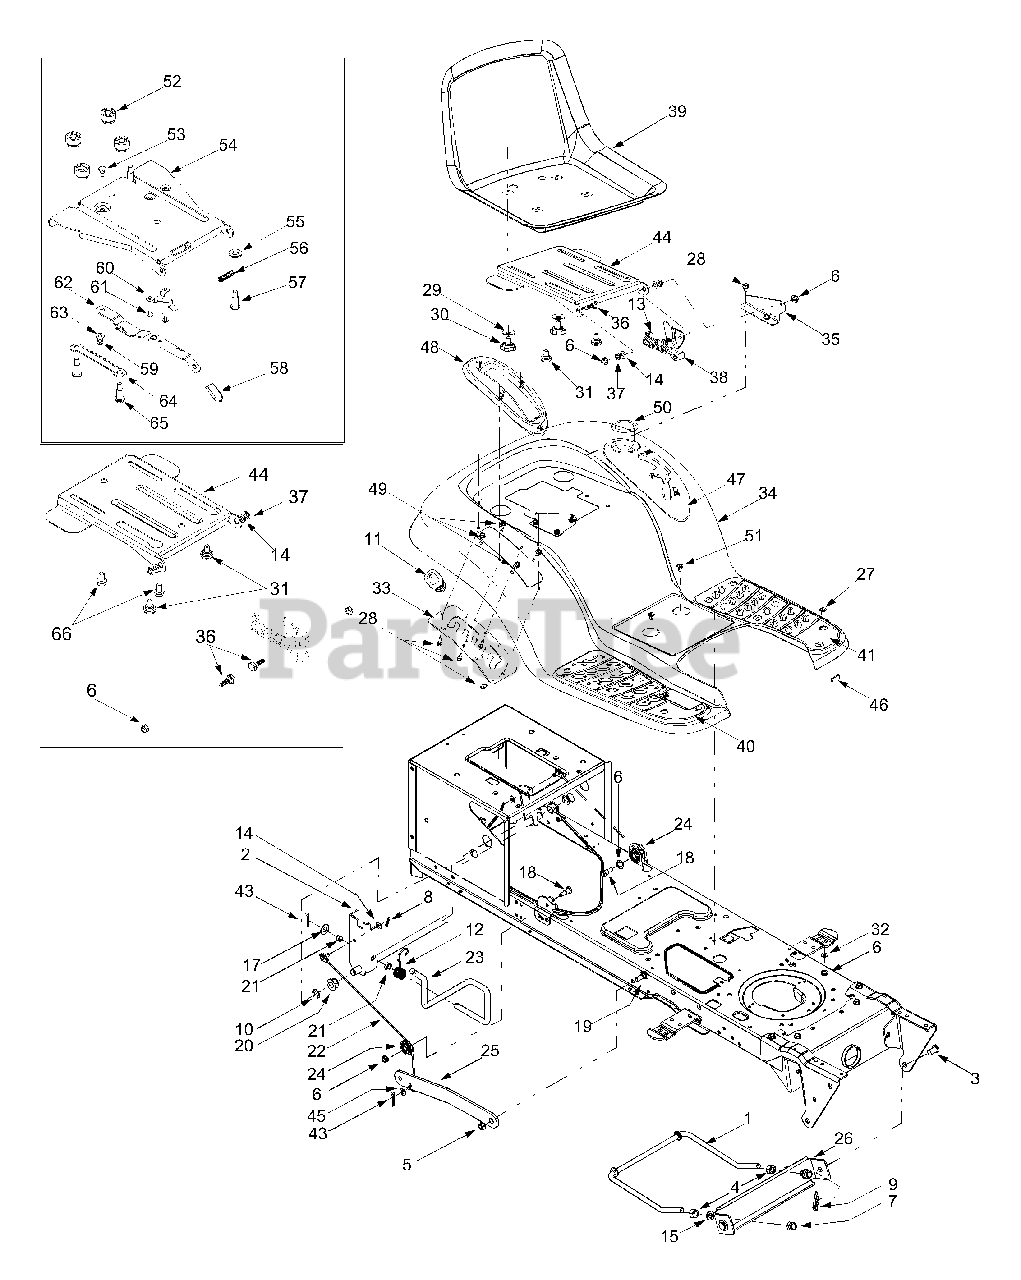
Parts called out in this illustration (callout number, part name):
1	Deck Stabilizer Rod
3	Clevis Pin, .5 x .78
4	Hex Nut, 1/2-13
5	Flange Lock Nut, 3/8-16
6	Flange Lock Nut, 5/16-18
7	Hex Nut, 1/2-13
8	Internal Cotter Pin
9	Internal Cotter Pin
10	E-Ring
11	Handle Grip
12	Torsion Spring
13	Extension Spring, .84 x 4.6
14	Flat Washer, 5/16
15	Lock Washer, 1/2
16	Flat Washer, .531 x 1.062 x .134
17	Flat Washer, .51 x 1.12 x .06
18	Hex Cap Screw, 5/16-18 x .62
19	Shoulder Screw, 3/8-16
20	Hex Flange Bearing
21	Snap Flange Bearing
22	Lift Cable, 16.16
23	Lift Handle
24	Roller Pulley
27	Carriage Bolt, 5/16 x .62
28	Self-tapping Screw, 5/16-18 x .625
29	Bell Washer, .390 x 1.13 x .062
30	Knob, 3/8-16
31	Shoulder Screw
32	Flat Washer, .349 x 1.0 x .063
36	Shoulder Screw
37	Speed Clip
38	Seat Lift Bracket
39	Seat: Low Back
40	Foot Pad RH, Rubber
41	Foot Pad LH, Rubber
42	Foot Pad Clips
43	Cotter Pin
45	Flat Washer, .344 x .62
46	Trim Strip
47	Lift Lever Cover
48	Shift Lever Cover w/ Cup Holder
49	Self-Tapping Screw, 1/4-15 x .75
50	Cup Holder
51	TT Screw, 1/4-20 x 0.5
52	Spacer: Seat Adjustment
53	Shoulder Screw 1/4-20
56	Compression Spring
57	Shoulder Screw 3/8-16
58	Grip: Seat Adjustment
59	Lock Nut 1/4-20
60	Seat Stop
61	B Screw #10-16 x 0.375
63	Flat Washer
64	Seat Adjustment Selector
65	Shoulder Screw 3/8-16
66	Hex Washer Hd. Screw
